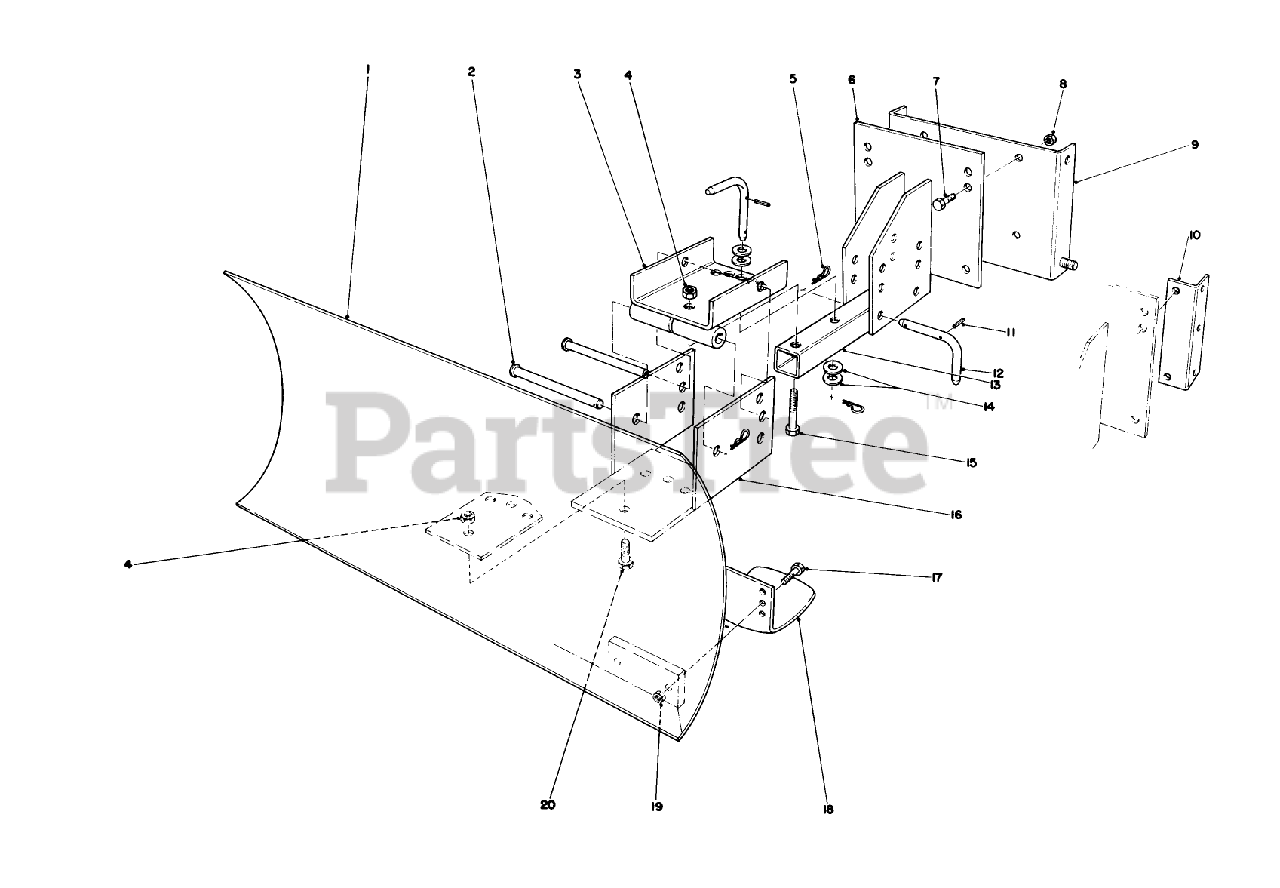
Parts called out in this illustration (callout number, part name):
1	Blade
2	PIN-CLEVIS
3	Swivel Bracket
4	1/2-13 CONELOCK NUT
5	PIN-HAIR
6	Mounting Plate
7	SCREW-HH
8	NUT-LOCK, CONE
9	Mounting Plate (Used with 826 & 1132 Units only)
10	Mounting Rail (used with 421 units only)
11	PIN-SPRING
12	Pivot Pin (Incl. Ref. #11)
13	Blade Tongue
14	WASHER-FLAT
15	SCREW-HH
16	Blade Adjustment
17	SCREW-HH
19	NUT-LOCK, CONE
20	SCREW-HH
